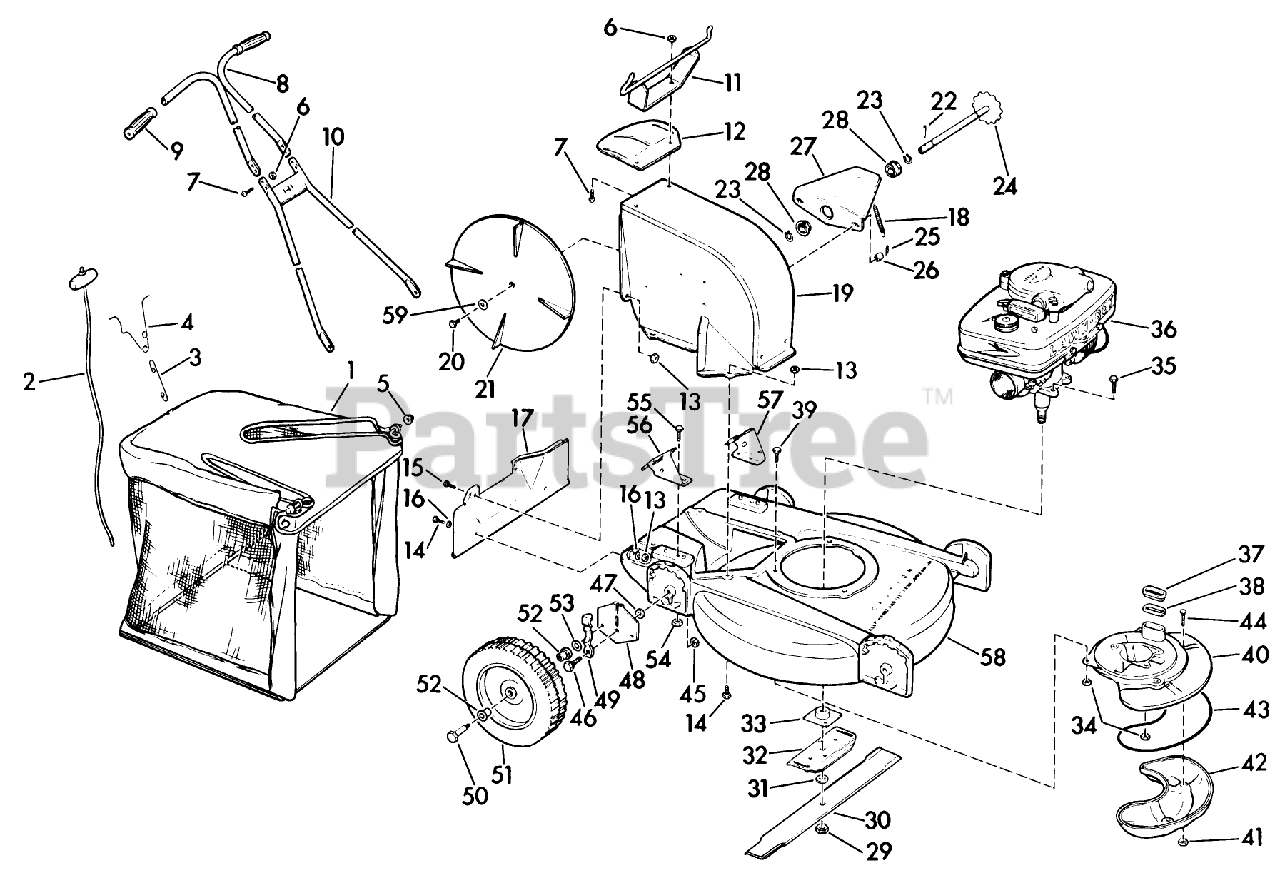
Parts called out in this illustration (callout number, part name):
1	Catcher Assy.-Complete
3	Hook-Catcher
4	Spring-Catcher Rope
6	STOP NUT
12	Deflector-Discharge
17	Bracket-Catcher Stop
18	Spring-Extension
21	Slinger
22	Pin-Spring, Drive Shaft
23	Ring-Retaining, Drive Shaft
26	Sleeve-Rubber
27	Bracket-Drive Shaft
28	Bearing-Ball, Nylon
29	NUT-BLADE
33	PLATE AND COLLAR ASM
41	LOCKNUT E
50	BOLT WHEEL
51	Wheel Assembly-Rear
53	WASHER WROUGHT
58	Housing-21"
